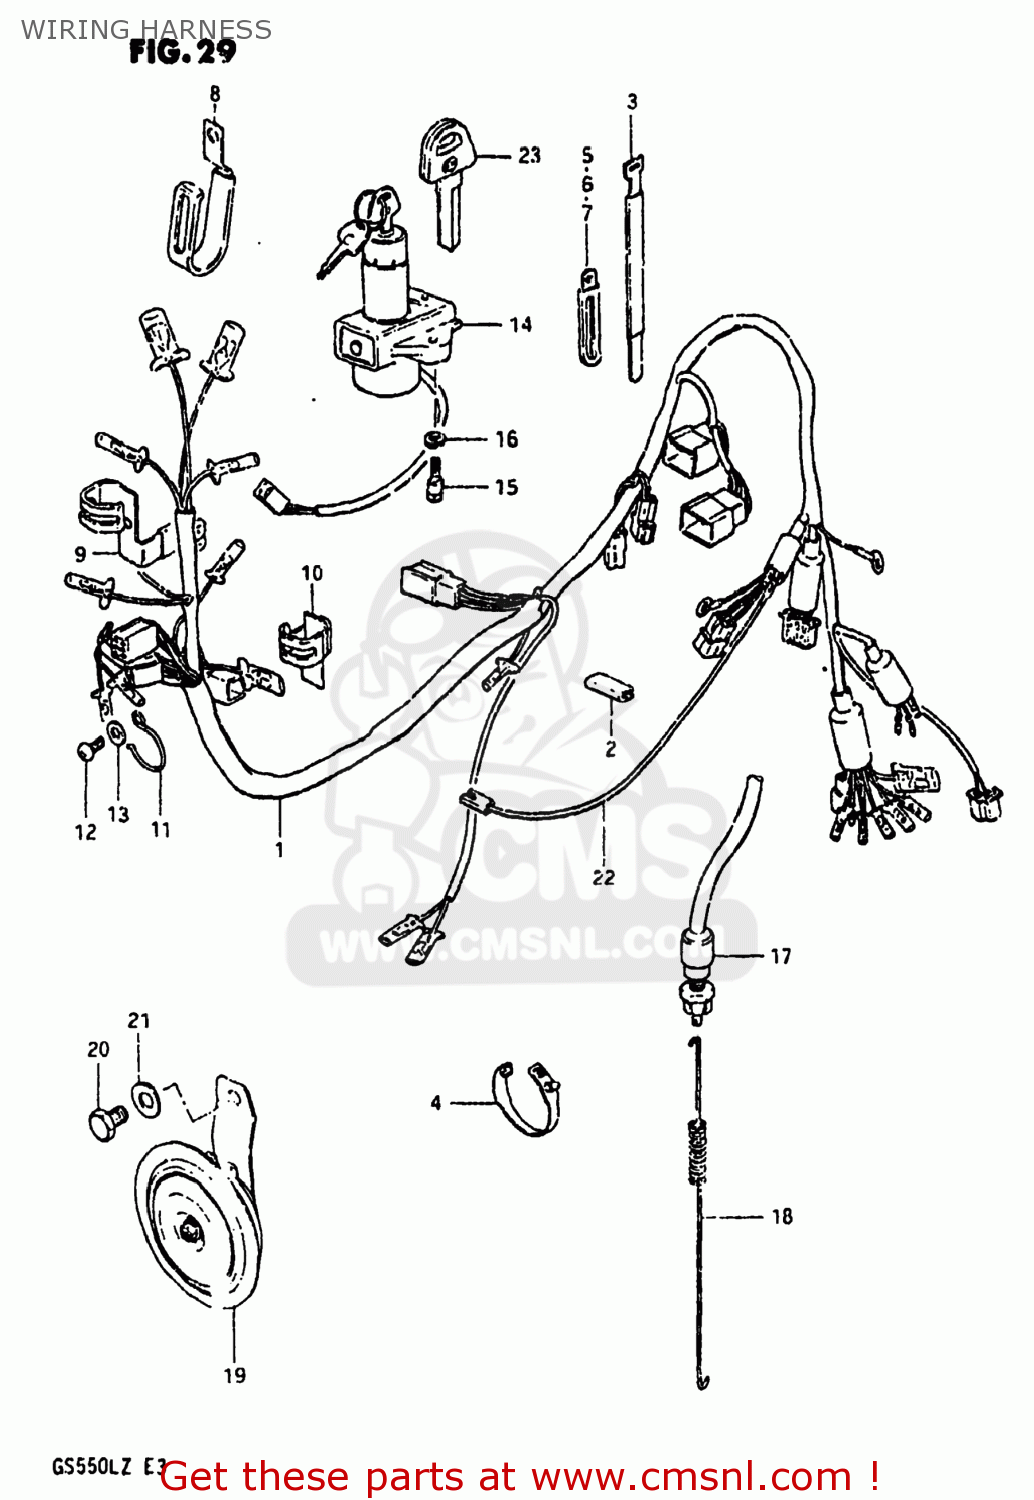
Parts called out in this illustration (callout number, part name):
1	HARNESS,WIRING
2	PROTECTOR,WIRING HARNESS
3	CLAMP(L:250)
4	CLAMP,L:88
5	CLAMP
6	CLAMP
7	CLAMP
8	CLAMP,WIRING HARNESS
9	CLAMP,WIRING HARNESS
10	CLAMP,WIRING HARNESS
11	GUIDE,WIRING HARNESS
12	SCREW 6X12
13	WASHER
14	SWITCH ASSY,IGNITION
15	BOLT
16	LOCK WASHER
17	SWITCH ASSEMBLY,STOP LAMP
18	SPRING
19	HORN ASSEMBLY
20	BOLT 8X12
21	WASHER
22	WIRE
23	KEY,BLANK
